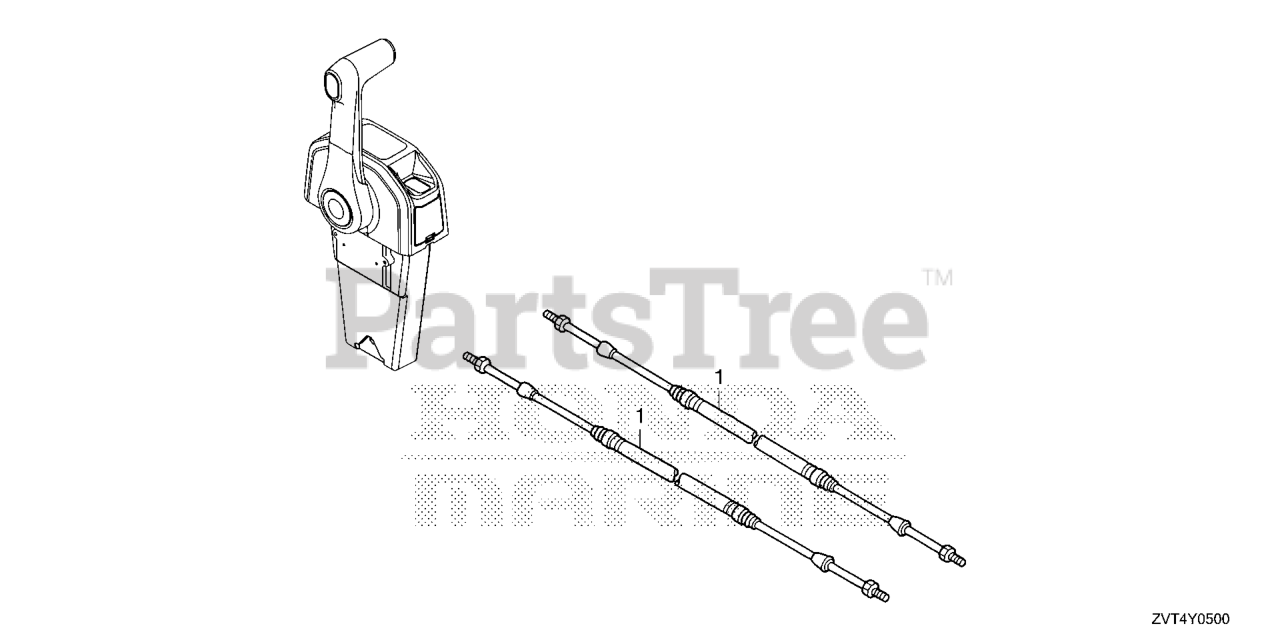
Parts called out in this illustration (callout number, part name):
1	CABLE, REMOTE CONTROL (5') (LOW FRICTION)
1	CABLE, REMOTE CONTROL (6') (LOW FRICTION)
1	CABLE, REMOTE CONTROL (7') (LOW FRICTION)
1	CABLE, REMOTE CONTROL (8') (LOW FRICTION)
1	CABLE, REMOTE CONTROL (9') (LOW FRICTION)
1	CABLE, REMOTE CONTROL (10'') (LOW FRICTION)
1	CABLE, REMOTE CONTROL (11'') (LOW FRICTION)
1	CABLE, REMOTE CONTROL (12'') (LOW FRICTION)
1	CABLE, REMOTE CONTROL (13'') (LOW FRICTION)
1	CABLE, REMOTE CONTROL (14'') (LOW FRICTION)
1	CABLE, REMOTE CONTROL (15'') (LOW FRICTION)
1	CABLE, REMOTE CONTROL (16'') (LOW FRICTION) (NOT AVAILABLE)
1	CABLE, REMOTE CONTROL (17'') (LOW FRICTION)
1	CABLE, REMOTE CONTROL (18') (LOW FRICTION) (NOT AVAILABLE)
1	CABLE, REMOTE CONTROL (1 9'') (LOW FRICTION)
1	CABLE, REMOTE CONTROL (20'') (LOW FRICTION) (NOT AVAILABLE)
1	CABLE, REMOTE CONTROL (21') (LOW FRICTION)
1	CABLE, REMOTE CONTROL (22') (LOW FRICTION) (NOT AVAILABLE)
1	CABLE, REMOTE CONTROL (2 3'') (LOW FRICTION)
1	CABLE, REMOTE CONTROL (24') (LOW FRICTION) (NOT AVAILABLE)
1	CABLE, REMOTE CONTROL (25') (LOW FRICTION)
1	CABLE, REMOTE CONTROL (26') (LOW FRICTION)
1	CABLE, REMOTE CONTROL (27') (LOW FRICTION)
1	CABLE, REMOTE CONTROL (28') (LOW FRICTION) (NOT AVAILABLE)
1	CABLE, REMOTE CONTROL (2 9') (LOW FRICTION)
1	CABLE, REMOTE CONTROL (30') (LOW FRICTION) (NOT AVAILABLE)
1	CABLE, REMOTE CONTROL (31') (LOW FRICTION)
1	CABLE, REMOTE CONTROL (32') (LOW FRICTION) (NOT AVAILABLE)
1	CABLE, REMOTE CONTROL (33') (LOW FRICTION)
1	CABLE, REMOTE CONTROL (34') (LOW FRICTION)
1	CABLE, REMOTE CONTROL (35') (LOW FRICTION)
